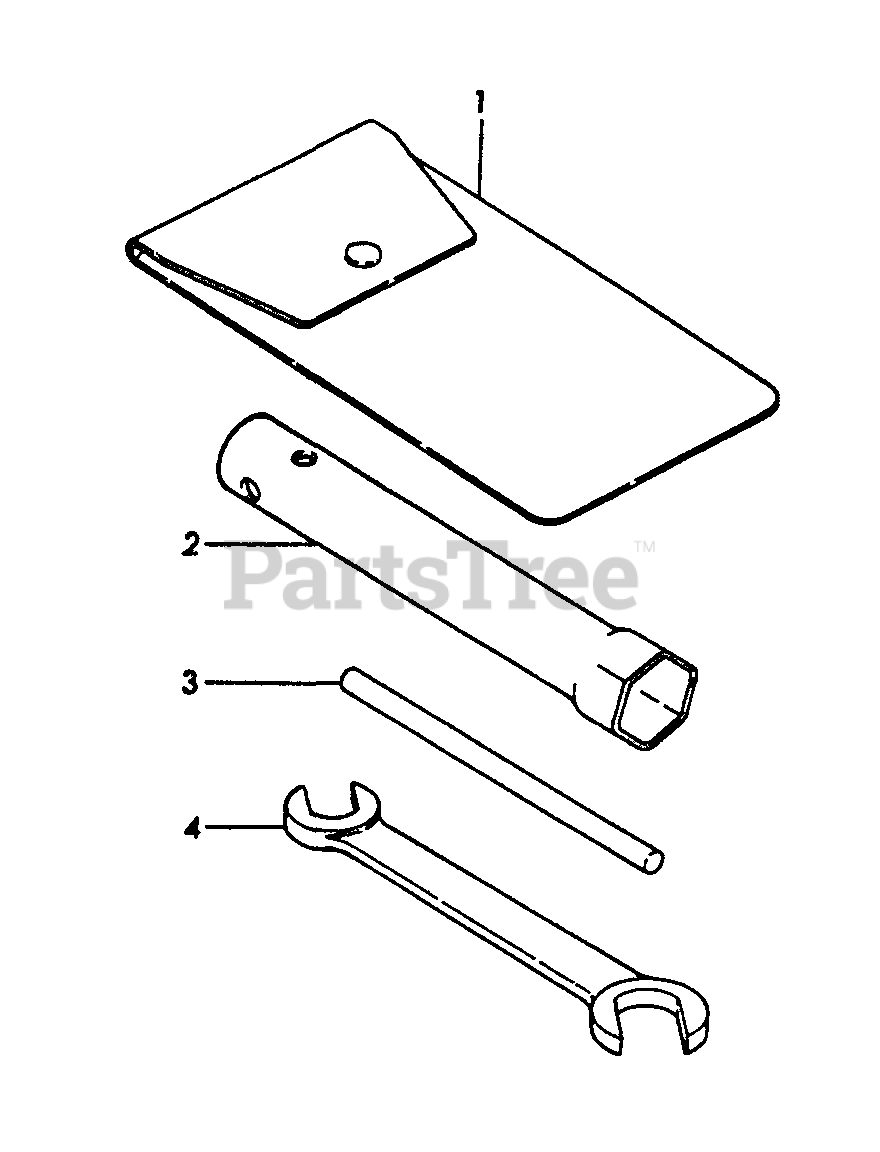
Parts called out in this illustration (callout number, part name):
1	BAG, TOOL
2	BOX SPANNER - 21
3	BAR
4	WRENCH 10×12
